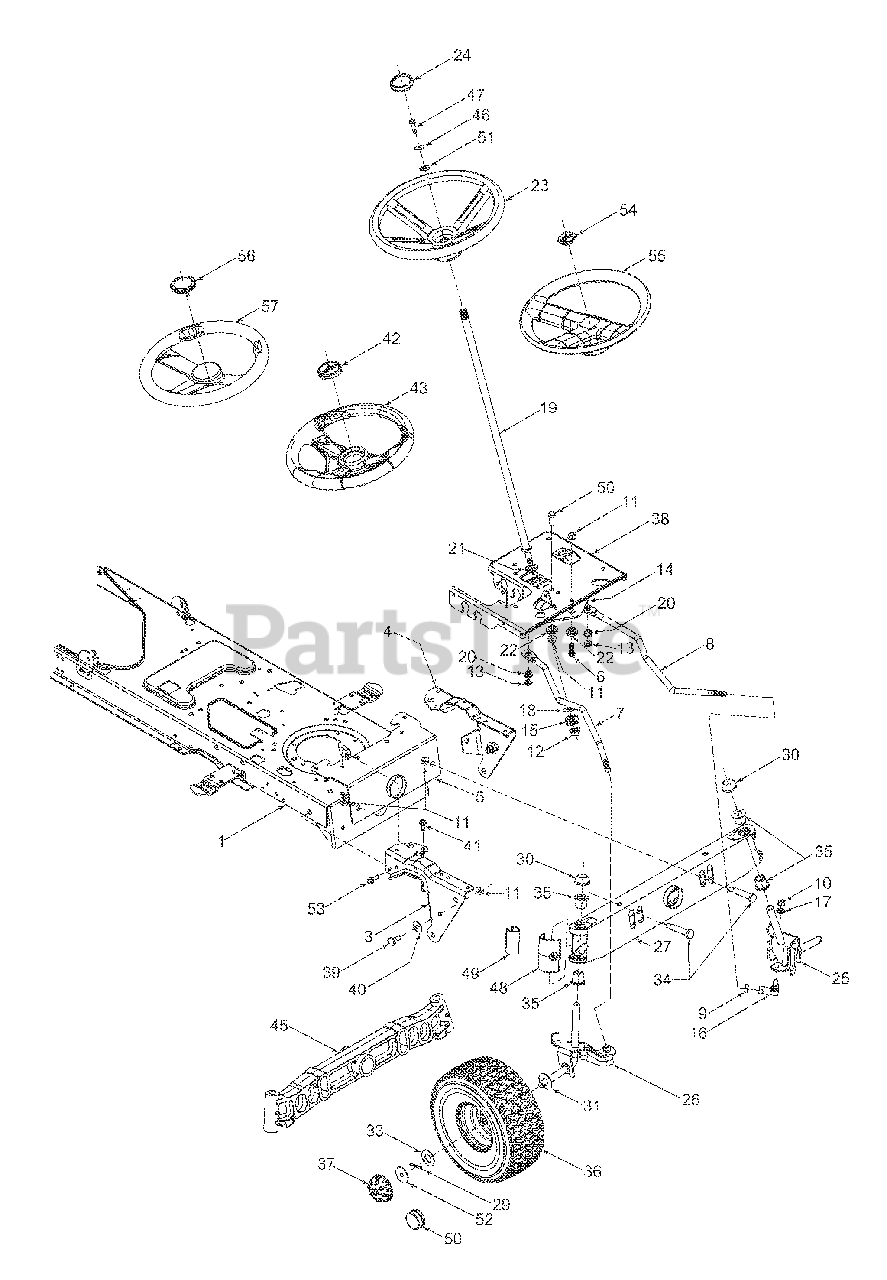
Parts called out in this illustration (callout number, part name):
6	Hex Cap Screw, 3/8-16 x 1.0 (Grade 5)
7	RH Drag Link
8	LH Drag Link
9	Jam Nut, 7/16-20 (Grade 2)
10	Hex Nut, 3/8-24 (Grade 2)
11	Flange Lock Nut, 3/8-16
12	Flange Lock Nut, 7/16-20
13	Flange Lock Nut, 5/16-18
14	Steering Gear, 11/90 Ratio
15	Steering Pinion Gear
16	Ball Joint, 7/16-20
17	Lock Washer, 3/8
18	Flat Washer, .51 x 1.12 x .06
19	Steering Shaft, .625 OD x 24.4
20	Plastic Bushing, .38 ID
21	Hex Flange Bearing, 5/8
22	Shoulder Spacer, .38 ID
23	Standard Steering Wheel, 13.25
24	Steering Wheel Cap, Round
25	LH Axle Assembly, .625 Diameter
26	RH Axle Assembly, .625 Diameter
29	Cotter Pin
30	Push Cap, .625
33	Flat Washer, .635 x 1.589 x .06
34	Shoulder Screw, .5 x 2.2, 3/8-16
35	Flange Bearing, .632 ID x .937 OD
37	Deluxe Hub Cap
39	Shoulder Screw, 3/8-16
40	Bell Washer, .39 x 1.13 x .062
41	Self-tapping Screw, 5/16-18 x .75
42	Deluxe Steering Wheel
43	Steering Wheel, Soft Grip
45	Cast Iron Pivot Bar
46	Bell Washer, .34 x .872
47	Hex Bolt, 5/16-18 x 1.0
48	Pivot Bar End Cap w/ Fitting
49	Pivot Bar End Cap w/o Fitting
50	Hex Screw, 3/8-16 x 1.0
51	Flat Washer, .406 x .875 x .105
52	Flat Washer, .35 x 1.59 x .062
53	Screw, Hex Washer, 5/16-18 x .87
54	Steering Wheel Cap
55	Steering Wheel
56	Steering Wheel Cap
57	Steering Wheel, Soft Grip
